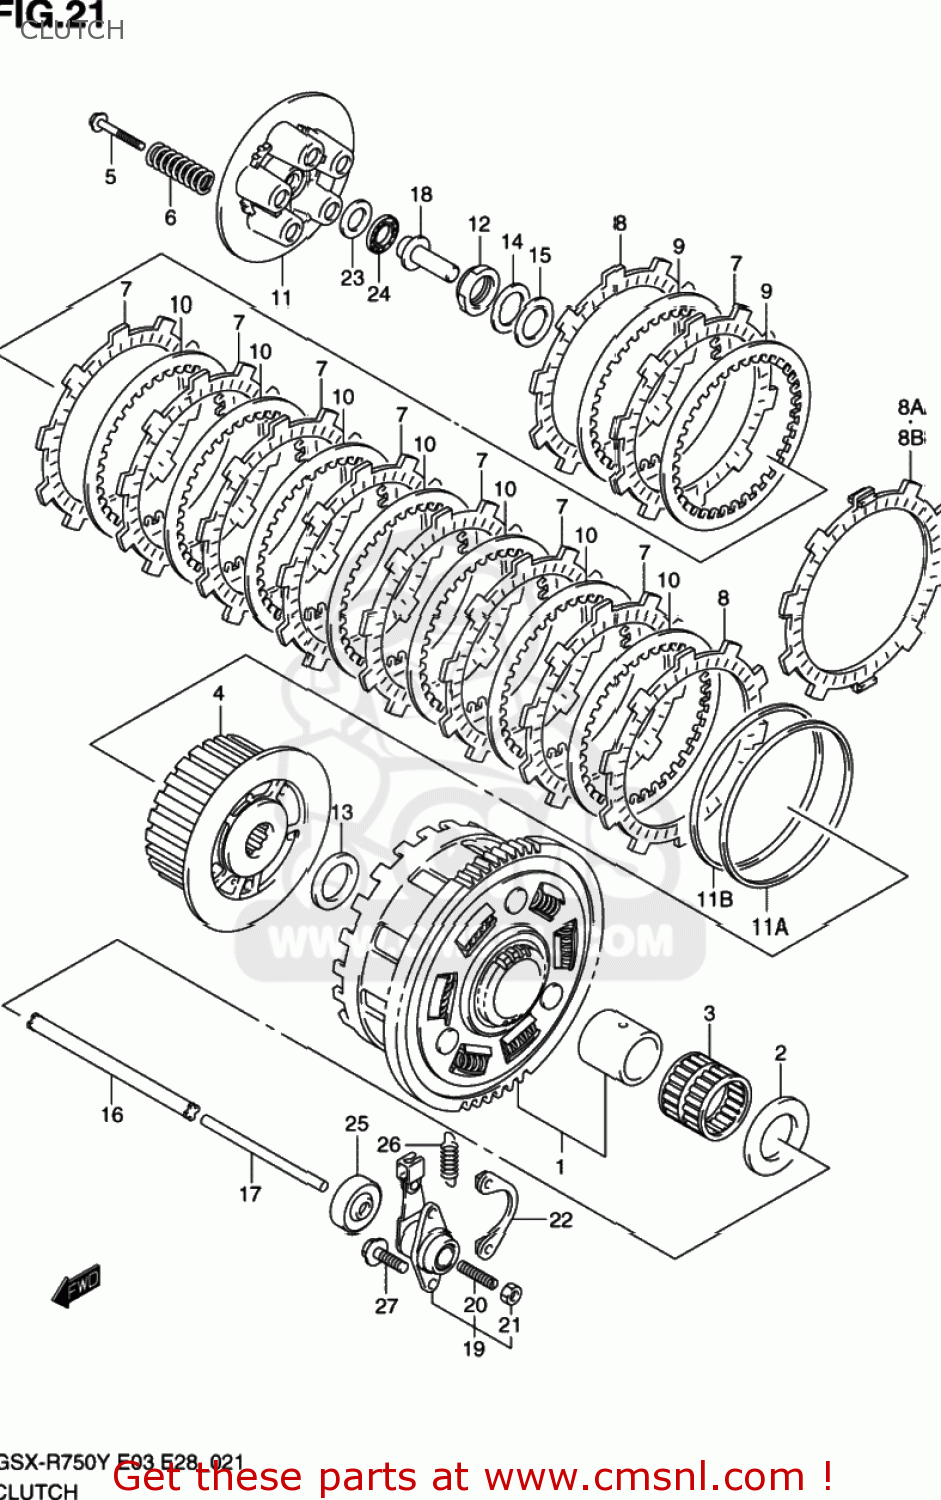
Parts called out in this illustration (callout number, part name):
1	GEAR ASSY,PRIM
2	WASHER(25X54X2.4)
3	BEARING(35X40X29.8)
4	HUB,CLUTCH SLEEVE
5	BOLT,CLUTCH SPRING
6	SPRING,CLUTCH
7	PLATE,CLUTCH DRIVE NO.1 (NAS)
8	PLATE,CLUTCH DRIVE (NAS)
8A	PLATE,CLUTCH D
8B	PLATE,CLUTCH DRIVE NO.3 (NAS)
9	PLATE,CLUTCH DRIVEN NO.1
10	PLATE,CLUTCH DRIVEN NO.2
11	DISC,CLUTCH PRESSURE
11A	SEAT,CLUTCH PLATE WAVE WASHER
11B	WASHER,CLUTCH PLATE WAVE
12	NUT
13	WASHER(25X50X2.5)
14	WASHER
15	SHIM(25X38X1)
16	ROD,CLUTCH
17	ROD,CLUTCH PUSH,L
18	PIECE,CLUTCH PUSH
19	SCREW ASSY,CLUTCH RELEASE
20	SCREW(6X25)
21	NUT
22	NUT,CLUTCH RLSE SCREW
23	WASHER(15.5X28X1)
24	BEARING(15X28X2)
25	SEAL,OIL(6X34X10)
26	SPRING
27	BOLT
